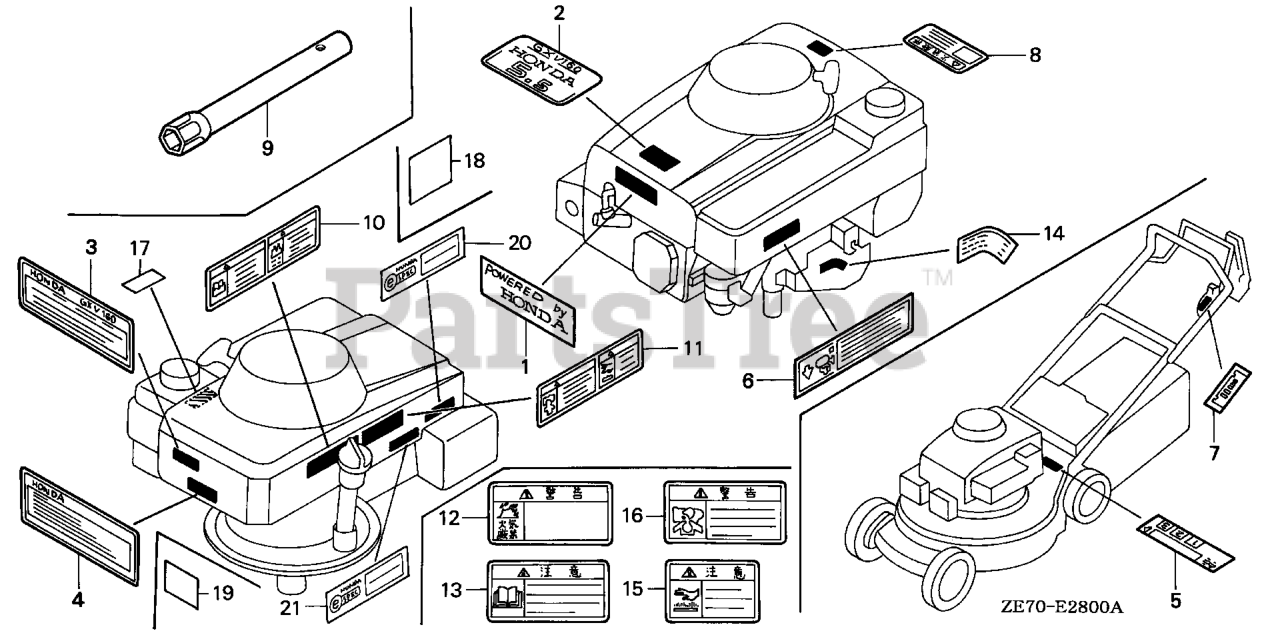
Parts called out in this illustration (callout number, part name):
2	MARK, EMBLEM (5.5 ES)
2	EMBLEM (5.5)
6	MARK, HONDA
9	WRENCH, BOX (P21)
19	MARK, TYPE (N12)
